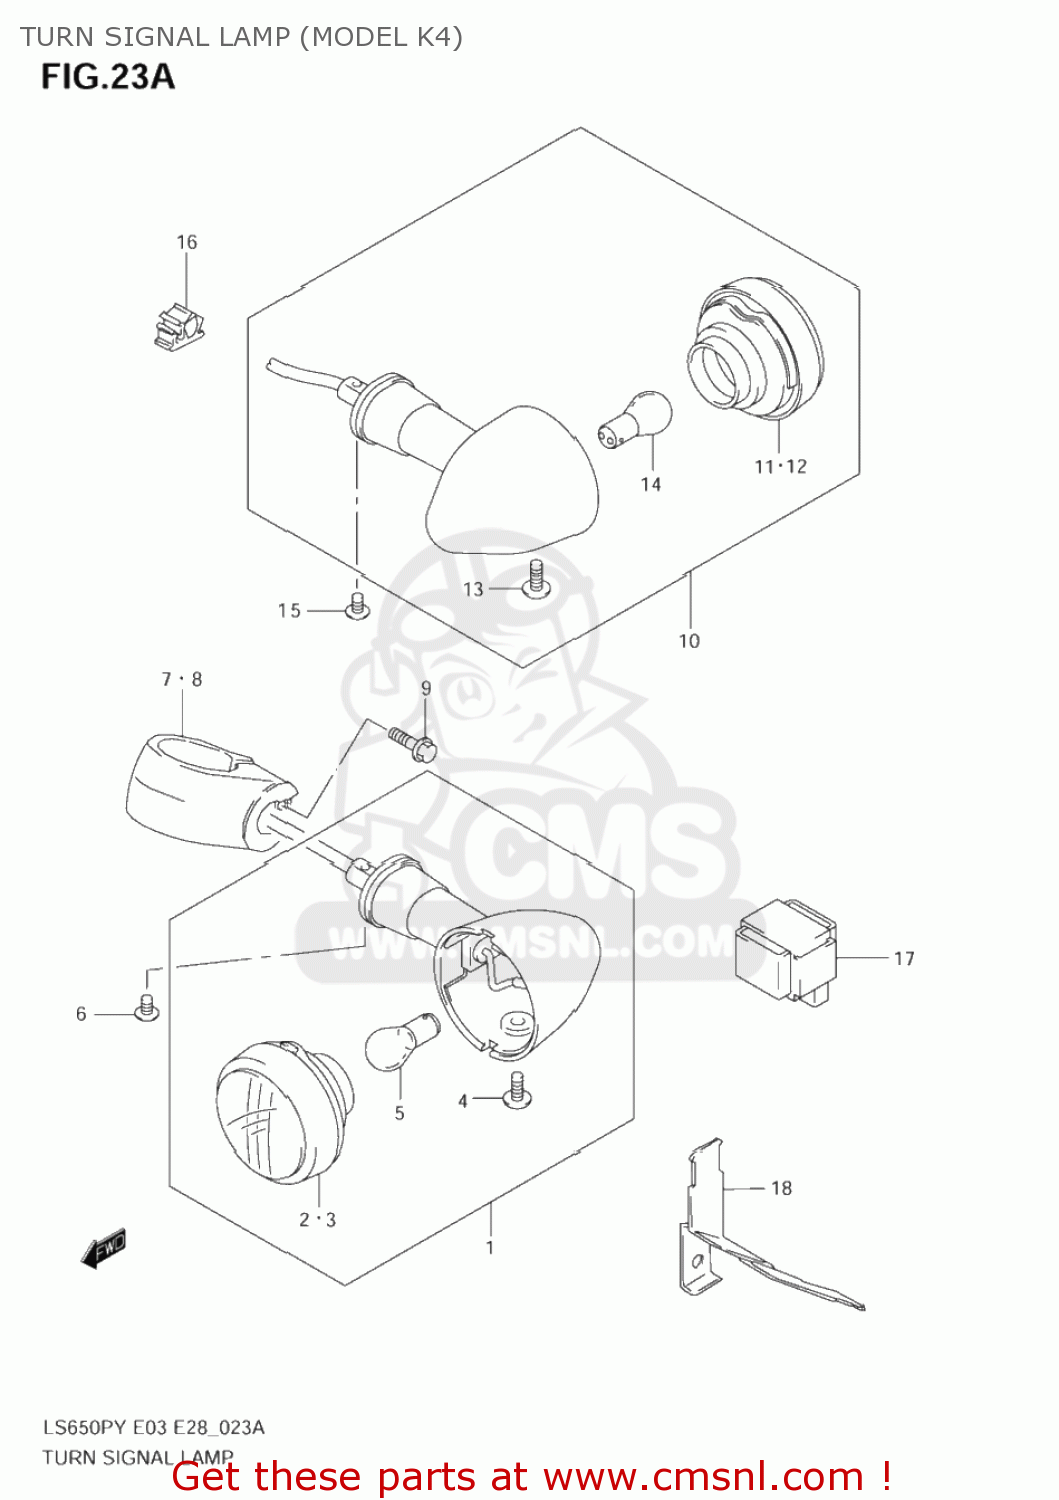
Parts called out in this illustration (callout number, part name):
1	LAMP ASSY,FR TURN SIGNAL,R
2	LENS
3	LENS
4	SCREW(4X10)
5	BULB(12V21/5W)
6	SCREW
7	BRACKET,FR TURNSIGNAL LAMP,R
8	BRACKET,FR TURNSIGNAL LAMP,L
9	BOLT
10	LAMP ASSY,RR TURNSIGNAL,R
11	LENS
12	LENS
13	SCREW(4X10)
14	BULB(12V21W)
15	SCREW
16	CLAMP
17	RELAY ASSY
18	BRACKET,TURNSIGNAL RELAY
